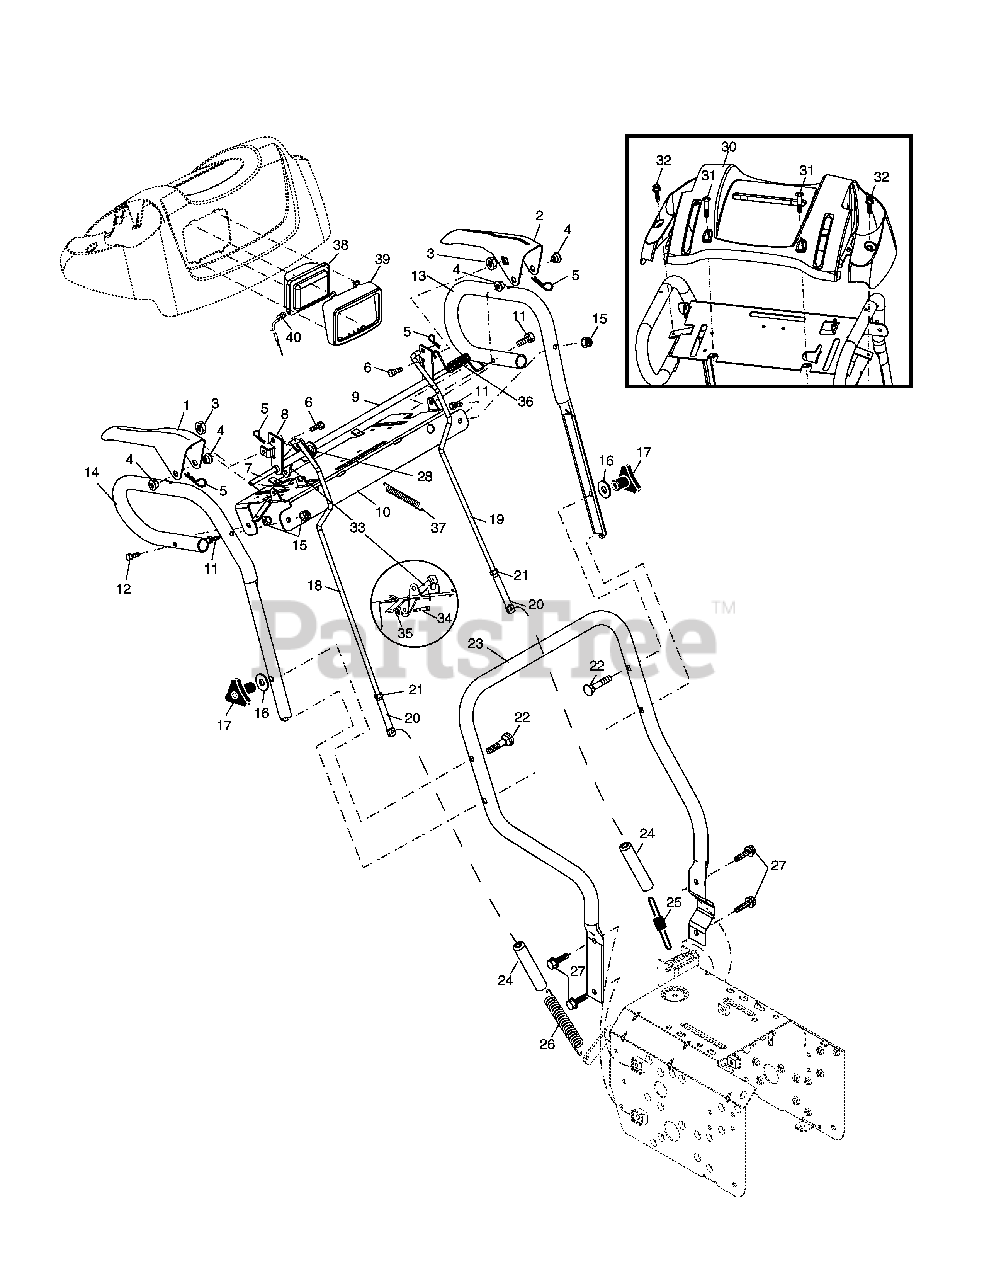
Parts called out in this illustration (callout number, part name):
1	Lever, Auger Control, RH
2	Lever, Traction Drive Control, LH
3	Nut, Cage 1/4-20
4	Bushing, Flange
5	Retainer, Hairpin
6	Screw, Hex Head 1/4-20 x 3/4
7	Rod, Interlock
8	Tube Assembly, Interlock, RH
9	Tube Assembly, Interlock, LH
10	Panel, Control
11	Screw, Hex Head 5/16-18 x 1-1/2
12	Screw, Hex Head 5/16-18 x 1-3/4
13	Handle Tube, LH
14	Handle Tube, RH
15	Nut, Lock 5/16-18
16	Washer, Flat 3/8
17	Knob, Handle
18	Rod, Auger Control
19	Rod, Traction Control
20	End, Control Rod
21	Nut, Hex, Jam 5/16-18
22	Bolt, Carriage 3/8-16 x 2-1/4
23	Handle Tube, Lower
24	Sleeve, Spring
25	Spring, Traction Drive
26	Spring, Auger Control
27	Screw, Hex Head 3/8-16 x 1
28	Clip, Panel
30	Console, Panel
31	Screw, Hex Head, Tapping #10-24 x 1-1/4
32	Screw, Hex Head, Tapping #10-24 x 1/2
33	Latch, Interlock
34	Bolt, Shoulder
35	Nut, Lock 1/4-20
36	Spring, Torsion
37	Spring, Interlock
38	Headlight, Flood
39	Bezel, Headlight
40	Wiring Harness, Headlight
